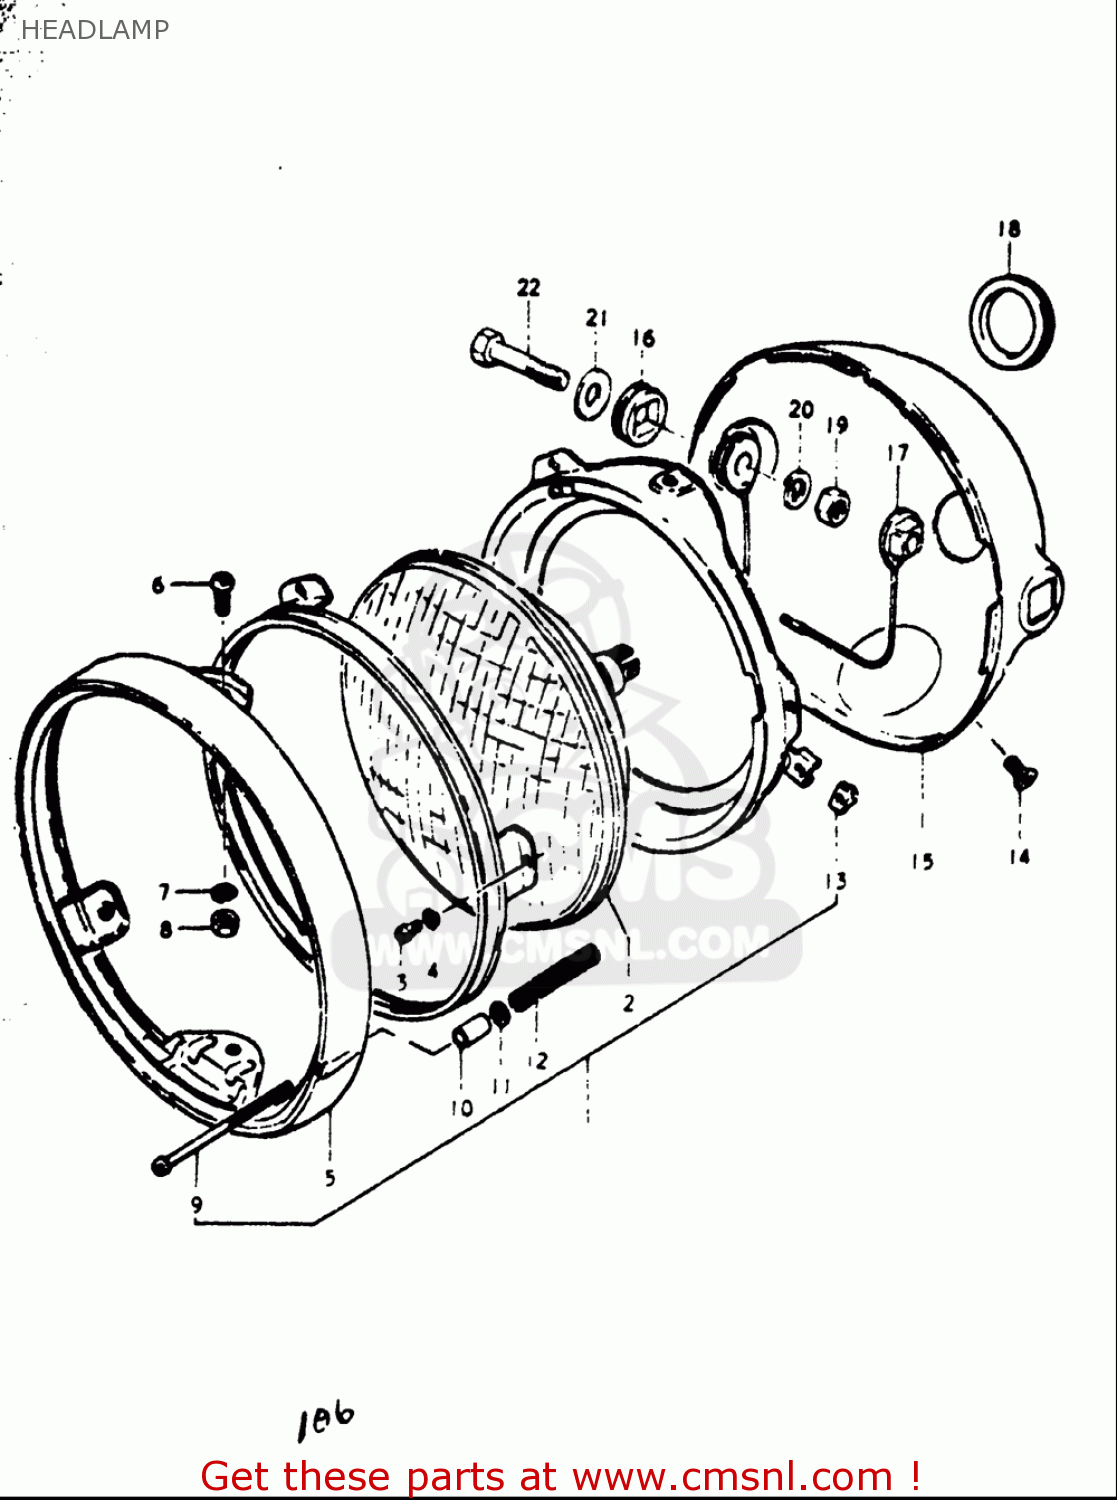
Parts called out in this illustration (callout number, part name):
3	SCREW
4	WASHER,LOCK
5	RIM,HEADLAMP
6	SCREW
7	WASHER,LOCK
8	NUT
9	SCREW
11	WASHER
13	NUT
14	SCREW
15	HOUSING,HEADLAMP
16	CUSHION,HOUSING
17	PIECE,ADJUSTER
18	GROMMET,HEADLAMP HOUSING
19	NUT
20	WASHER,LOCK
21	WASHER
22	BOLT
